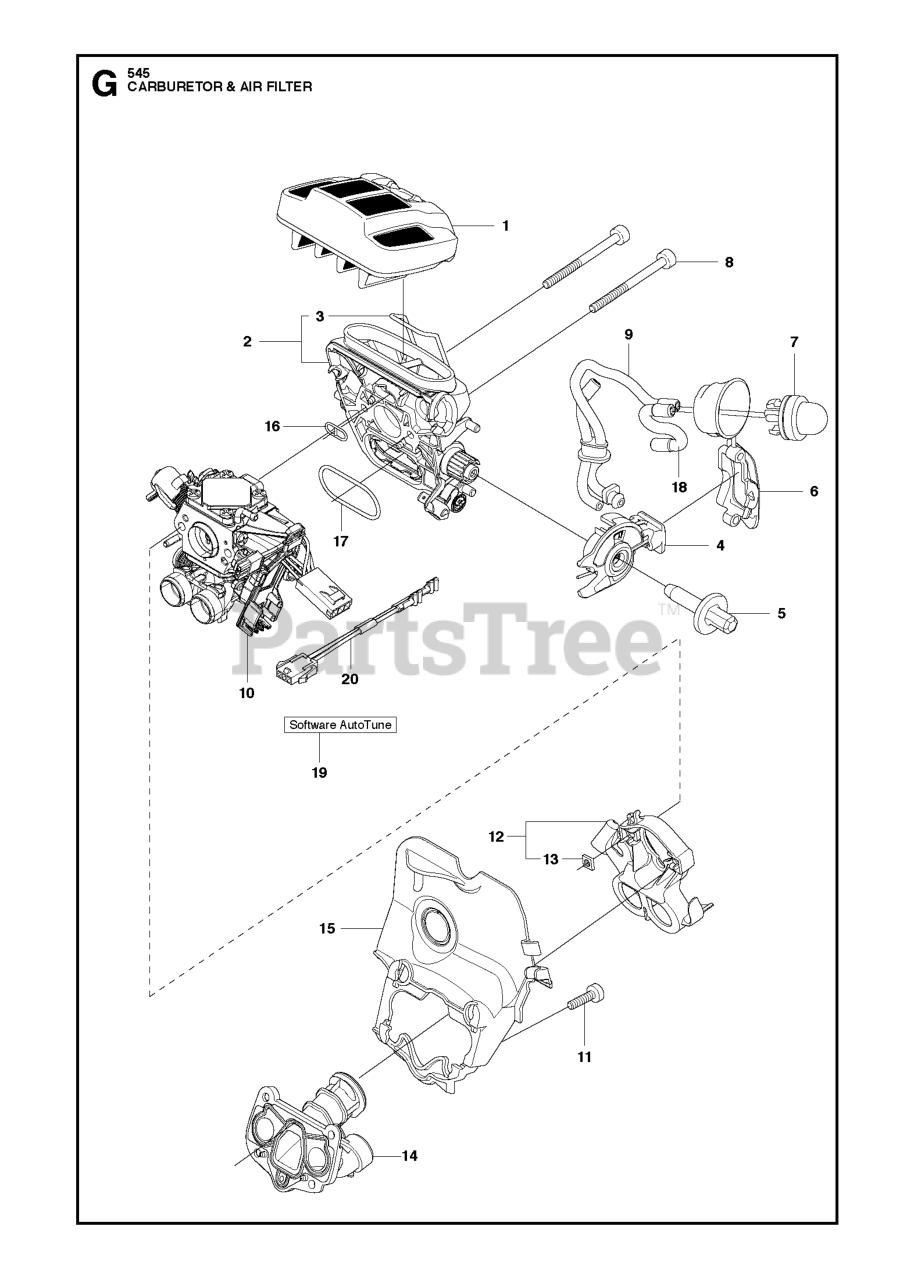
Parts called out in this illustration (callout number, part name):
1	AIR FILTER ASSY
2	FILTER HOLDER ASSY
3	SHACKLE
4	CHOKE CONTROL ASSY
7	AIR PURGE BUBBLE
9	FUEL HOSE
10	RP CARBURETTOR
11	SCREW IHSCM
12	FLANGE
13	NUT
14	INLET PIPE ASSY
15	INTERMEDIATE WALL
19	Husqvarna TBD
20	WIRING ASSY
